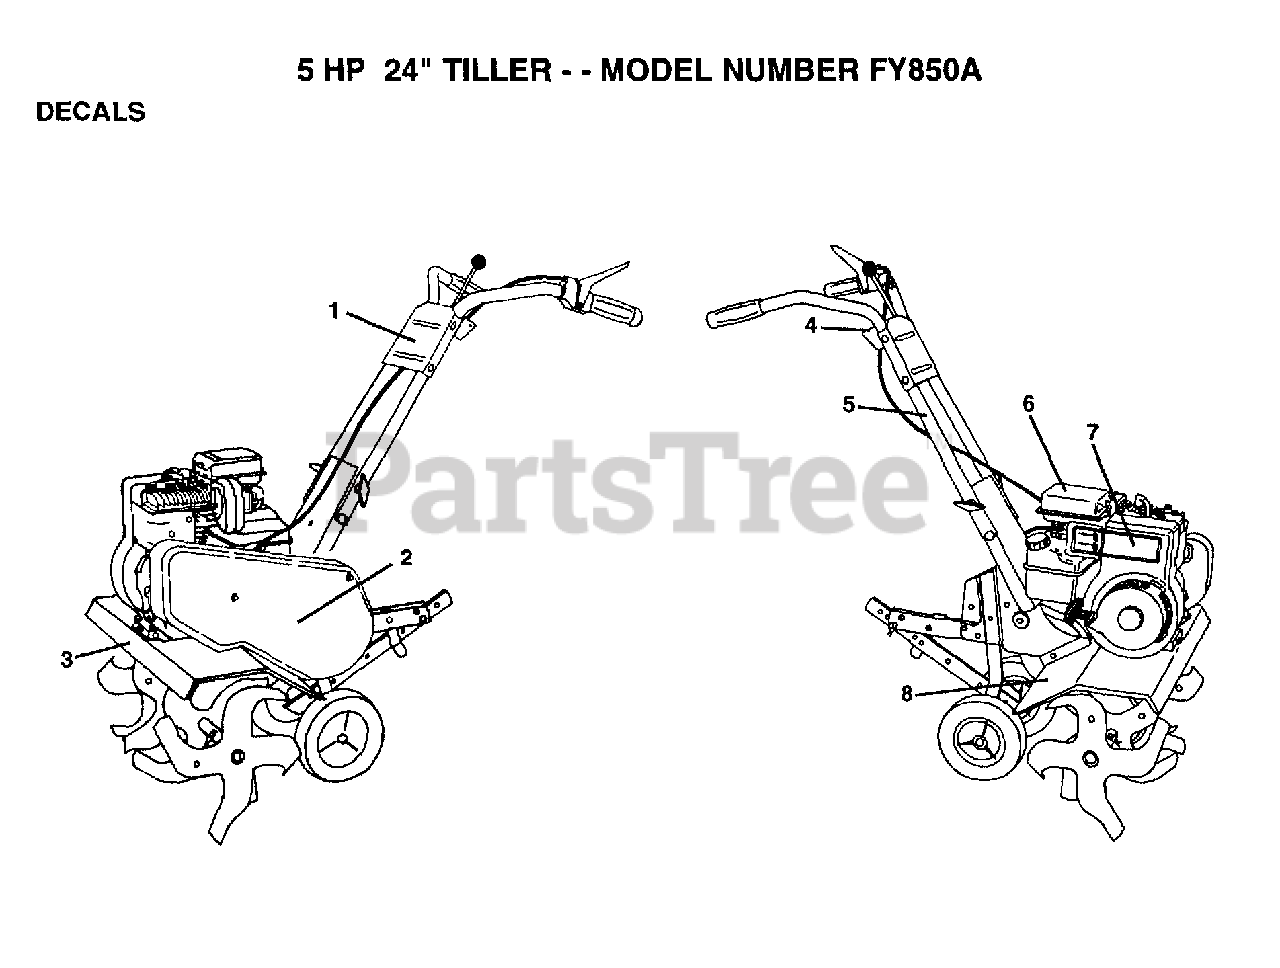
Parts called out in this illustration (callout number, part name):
1	DECAL HANDLE BRKT
2	DECAL.BELT.GUAR
3	DECAL TINE SHIELD
4	DECAL REVERSE
5	DECAL TI
6	DECAL TI
